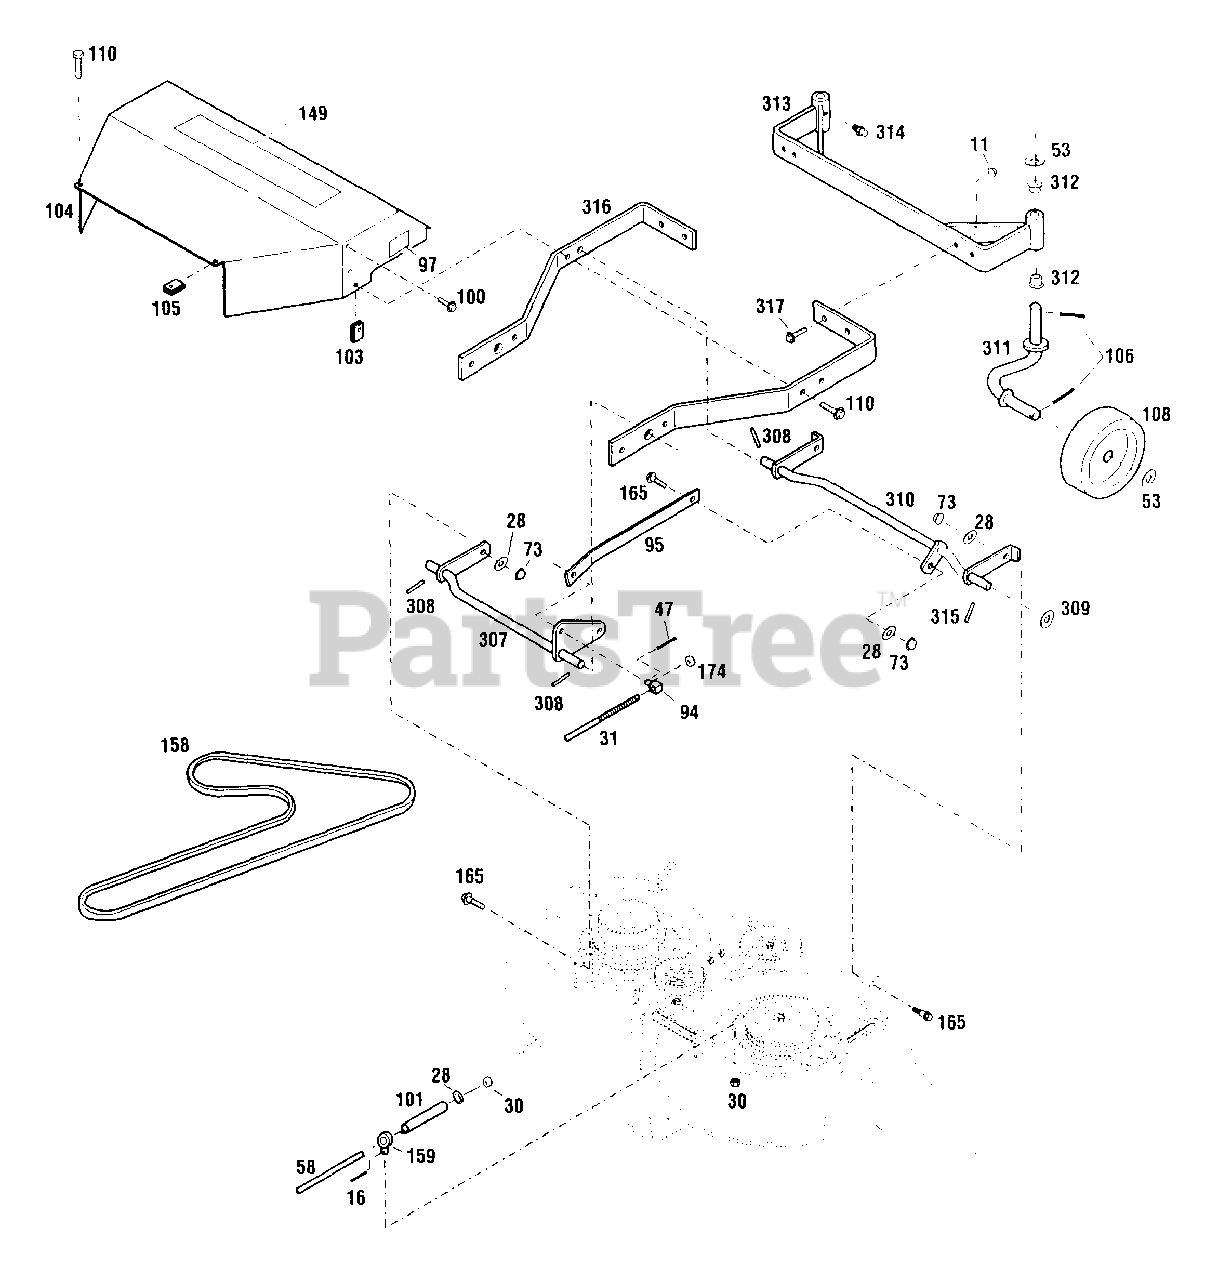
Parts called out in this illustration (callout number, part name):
11	Flange Locknut, 3/8-16
16	Cotter Pin, 3/32 x 5/8
28	Flat Washer, 3/8
30	Locknut, 3/8-16
31	Lift Crank
47	Cotter Pin
53	Special Washer
58	Lower Blade Rod
73	Flange Locknut, 3/8-16
94	Pivot Block
95	Leveler Bar
97	Cutting Height Decal
100	Tap Screw, #8 x 3/8
101	Compression Spring
103	Speed Nut, 5/16-18
104	Belt Guard
105	Speed Nut, 5/16-18
106	Cotter Pin
108	Gage Wheel
110	Flange Lock Screw, 5/16 x 3/4
149	Logo Decal
158	V-Belt
159	Eye Bolt
165	Shoulder Bolt
174	Toplock Nut
307	Rear Lift Assembly
308	Roll Pin, 1/4 x 1
309	Flat Washer, 5/8
310	Front Lift Assembly
311	Spindle Assembly
312	Flange Bearing
313	Gage Support
314	Grease Fitting
315	Drive Pin, 1/4 x 3
316	Mower Support
317	Whizlock Screw, 3/8-16 x 1
